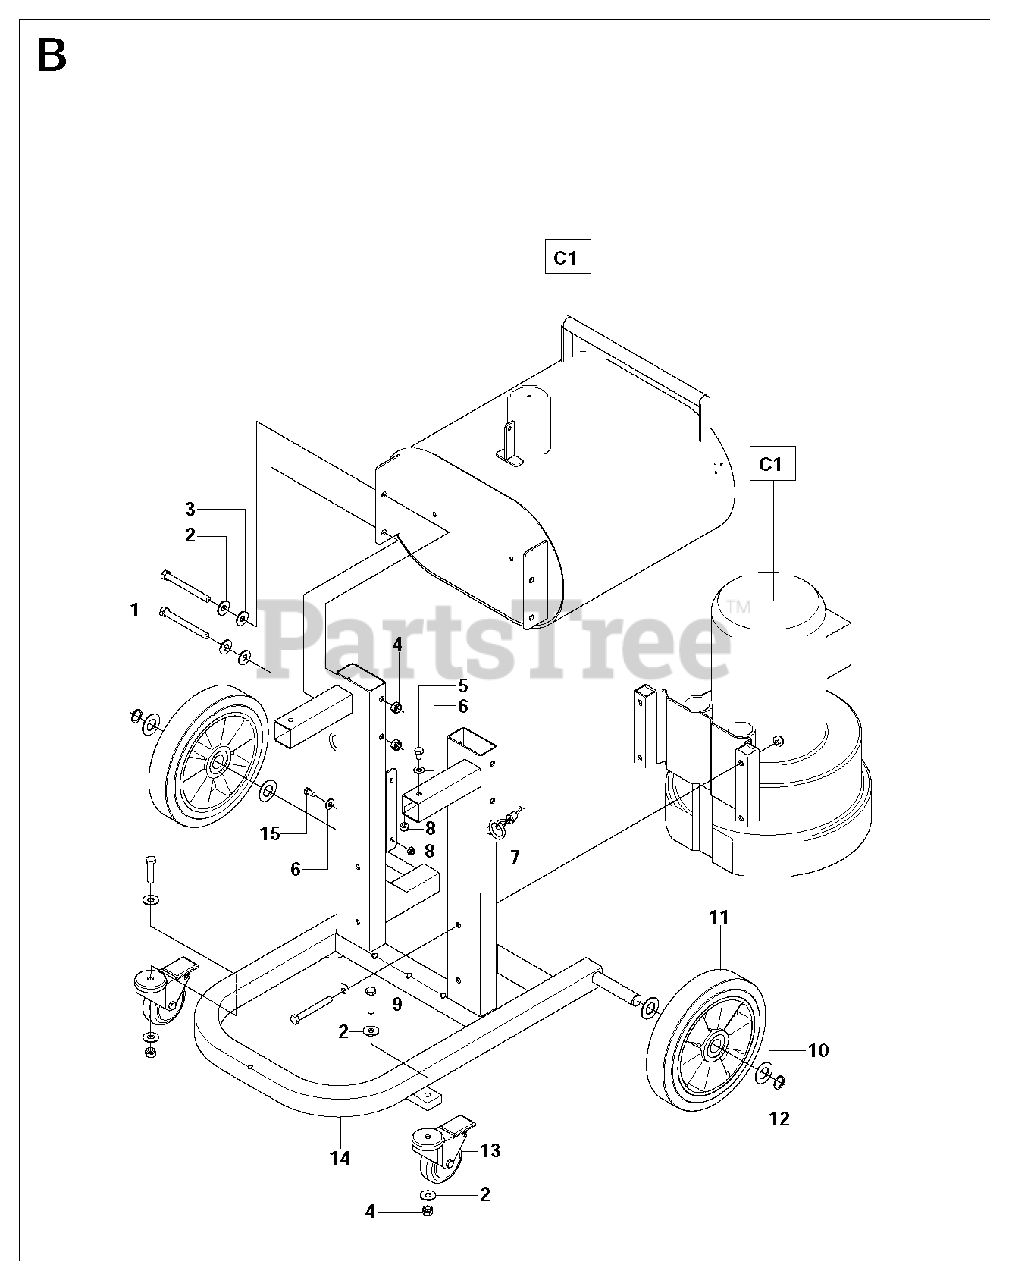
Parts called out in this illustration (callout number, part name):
2	WASHER
6	WASHER
8	HEXAGON LOCKING NUT
